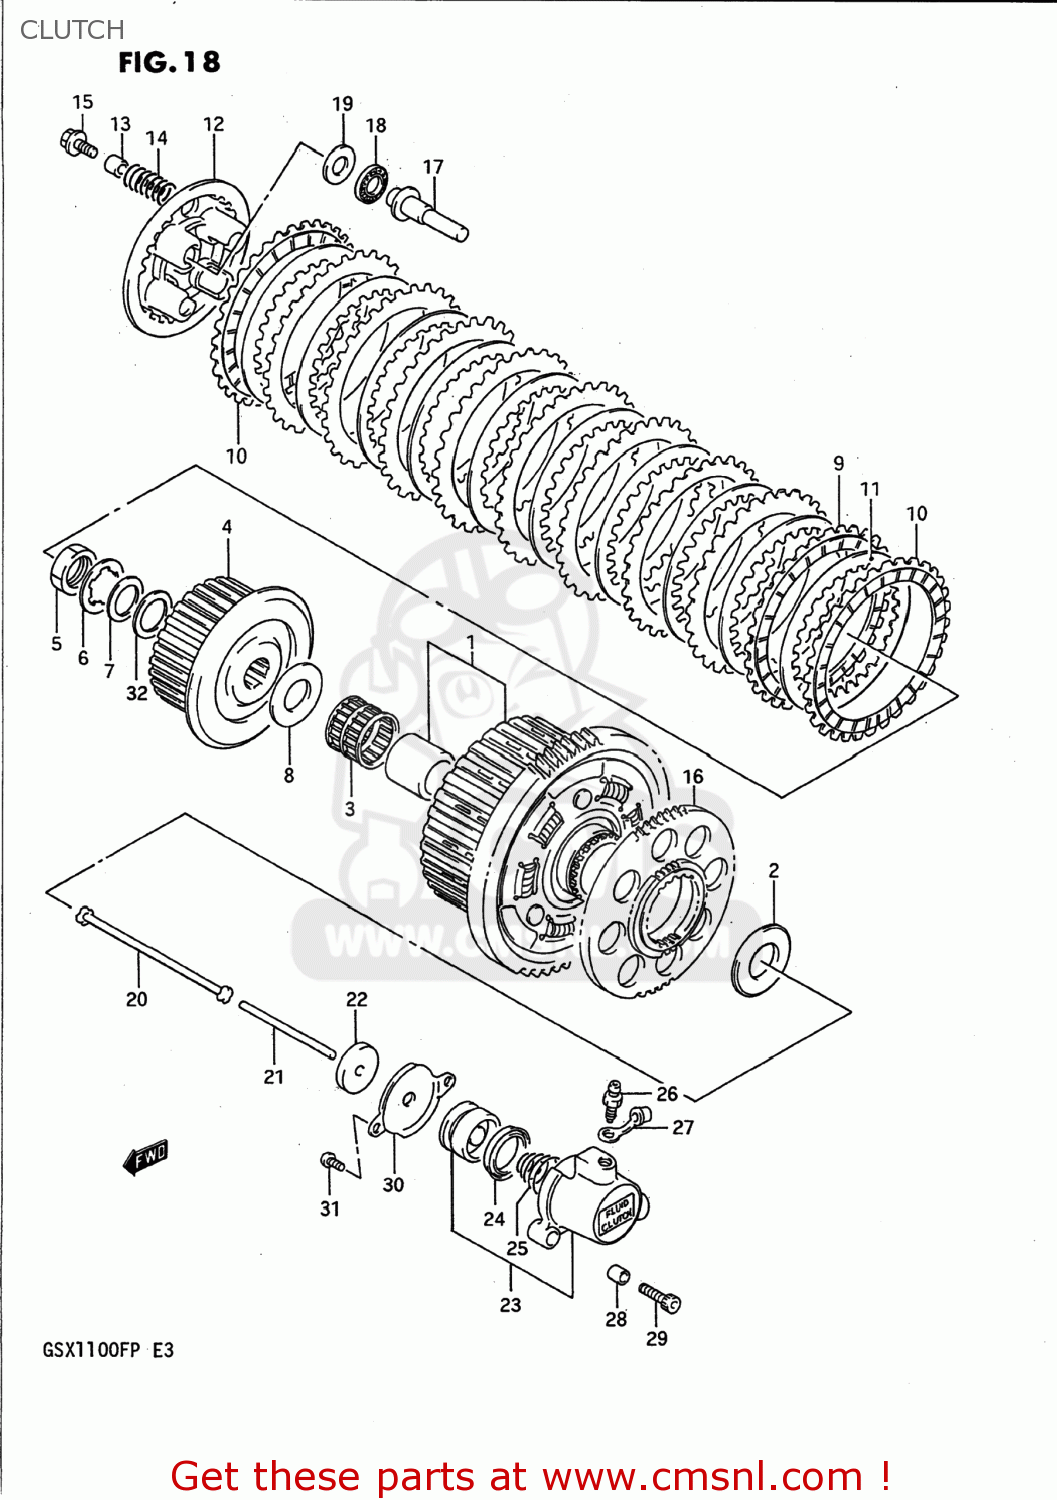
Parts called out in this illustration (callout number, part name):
1	GEAR ASSEMBLY,PRIMARY DRIVE
2	WASHER(25X54X2.5)
3	BEARING(35X40X35.8)
4	HUB,CLUTCH SLEEVE
5	NUT
6	WASHER,LOCK
7	WASHER
8	WASHER(25X50X2.5)
9	PLATE,CLUTCH DRIVE NO.1 (NAS)
10	PLATE,CLUTCH DRIVE NO.2 (NAS)
11	PLATE,CLUTCH DRIVEN (NAS)
12	DISC,CLUTCH PRESSURE
13	SPACER(6.2X12X14)
14	SPRING
15	BOLT
16	GEAR,GENERATOR DRIVE
17	PIECE,CLUTCH PUSH
18	BEARING(15X28X2)
19	WASHER
20	ROD,CLUTCH
21	ROD,CLUTCH PUSH,L
22	SEAL,OIL(6X34X5.5)
23	CYLINDER,CLUTCH RELEASE
24	CUP,CLUTCH CYLINDER
25	SPRING,CLUTCH CYLINDER
26	BLEEDER
27	CAP,BLEEDER
28	PIN
29	BOLT
30	PLATE,CLUTCH PUSH ROD
31	SCREW
32	SHIM
